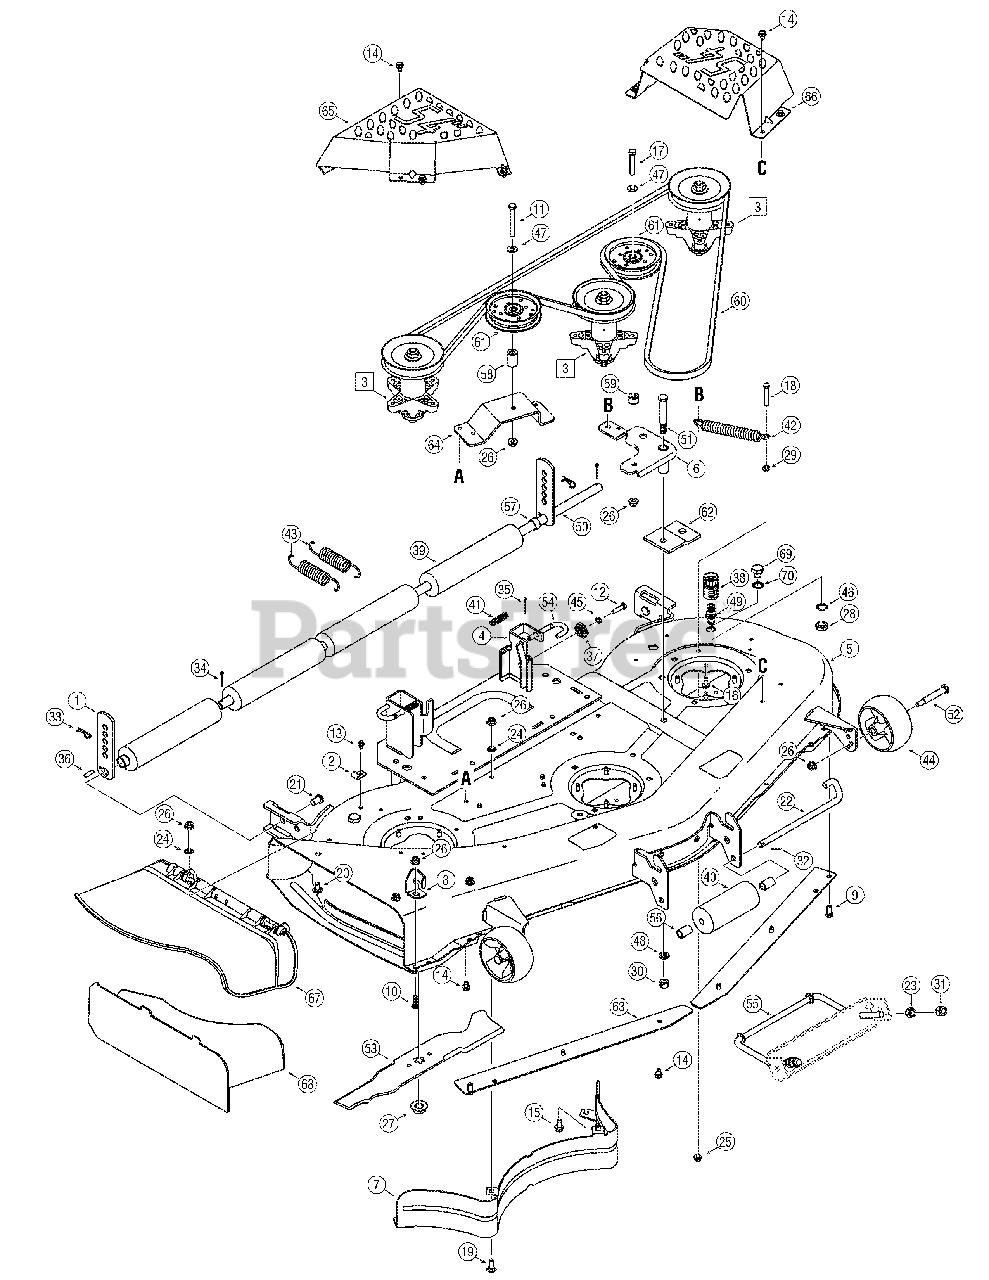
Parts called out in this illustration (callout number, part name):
2	Bracket, Hook, Retainer
3	Spindle Assembly, Pulley
9	Hex Screw 3/8-16 x 0.75
10	Hex Screw 3/8-16 x 1.0
11	Screw, 3/8-16 x 3.00
12	Hex Screw, 5/16-18 x 1.25
13	Screw, 1/4-20 x.500
14	Screw, 5/16-18 x 0.500
15	Screw, 3/8-16 x.750
16	LD Screw 5/16-18 x 0.75
17	Hex Screw, 3/8-16 x 2.25
18	Hex Screw, 5/16-18 x 2.00
19	Bolt, Carriage, 3/8-16 x 1.0
20	Carriage Bolt 3/8-16 x.75
21	Pin, Clevis,.50 Dia x.78
22	Pin, Roller,.5" Dia x 10.06.
23	Hex Nut, 1/2-13
24	Push Nut Retainer
25	Nut, Flange Lock, 5/16-18
26	Nut, Lock, Flange, 3/8-16
27	Nut, Hex Flange, 5/8-18
29	Nut, Hex, 5/16-18, Gr5
30	Nut, Hex Lock, 1/2-13
31	Hex Lock Nut, 1/2-13
32	Pin, Cotter, 3/32 x 1.00
33	Pin, Click,.092 x 1.64
35	Pin, Cotter, 1/8 x 1.25
36	Pin, Spring 1/4 Dia x 1.00
37	Adjustment, Deck, Gear
38	Water Nozzle Adaptor
39	Roller, Deck
40	Front Roller
41	Spring, Compression
42	Spring, Ext., .94 Dia. x 6.74
43	Spring, Ext., 1.15 Dia. X 5.99
44	Deck Wheel, 5" Dia.
45	Lock Washer
46	Lock Washer, 5/8"
47	Washer, Flat.406 x.875 x.059
49	Deck Wash Water Nozzle
50	Shaft,.750 x.47.12
51	Shoulder Screw
52	Shoulder Screw
53	Blade, 18.50"
54	Deck Rels. Hndl. Rod,.375 Dia
55	Rod, Deck Adjust
56	Spacer.550 ID x.755 OD x 1.1
57	Spacer,.82 ID x 1.00 OD x.53
58	Spacer,.380 x.900 x 1.313
59	Spacer,.385 ID x.88 x.64
60	Belt, V-Type, B Section
61	Pulley, Idler, 4.25 Dia.
67	Chute Assembly
69	Plug, Bolt, M16 x 1.5
70	Washer, Flat, .64 x 1.24 x .06
